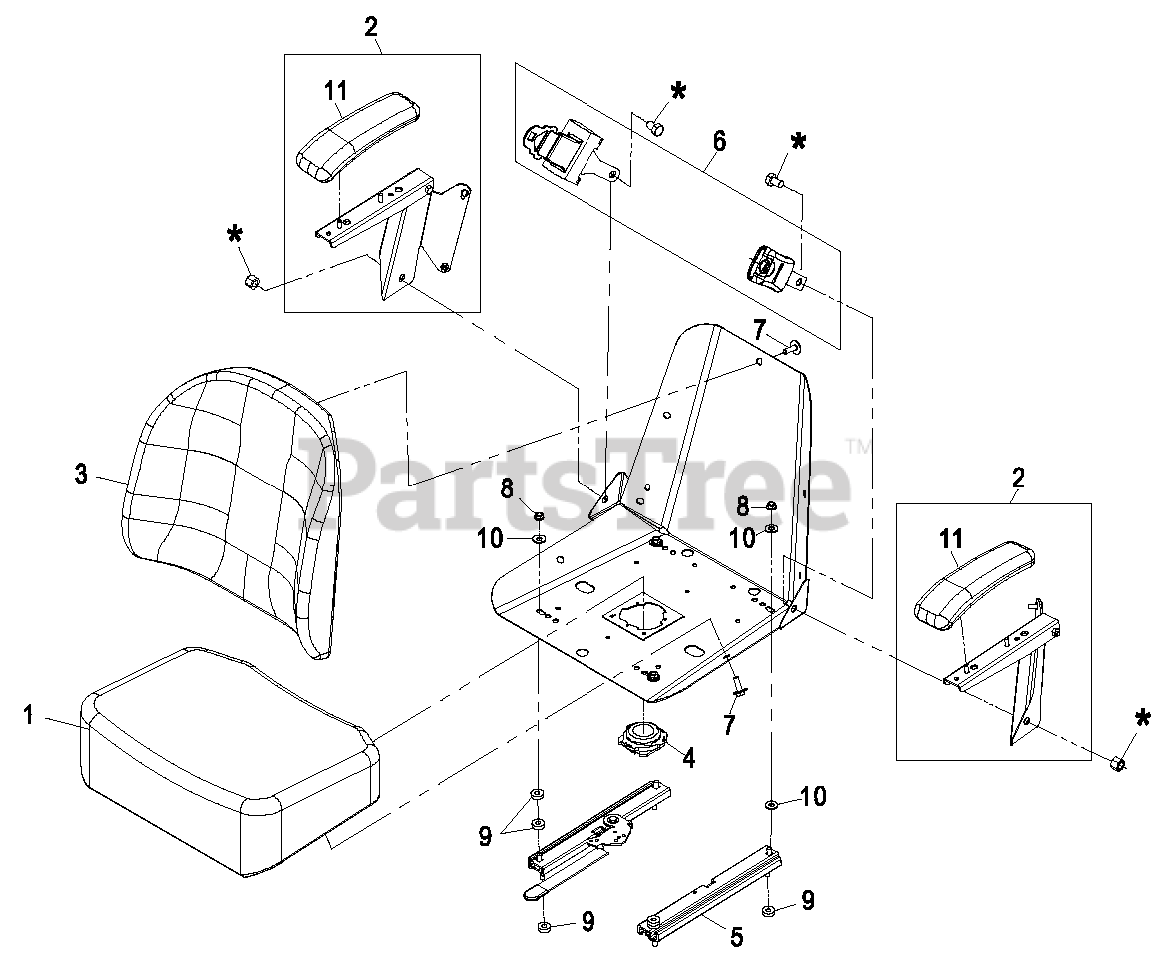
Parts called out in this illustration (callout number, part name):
1	CUSHION-SEAT
2	ARMREST KIT
3	CUSHION,SEAT BACK
4	SWITCH-SEAT
5	TRACK-SEAT
6	SEAT BELT KIT
7	BOLT-SEAT
10	WASHER-FLAT
11	CUSHION-REST, ARM
